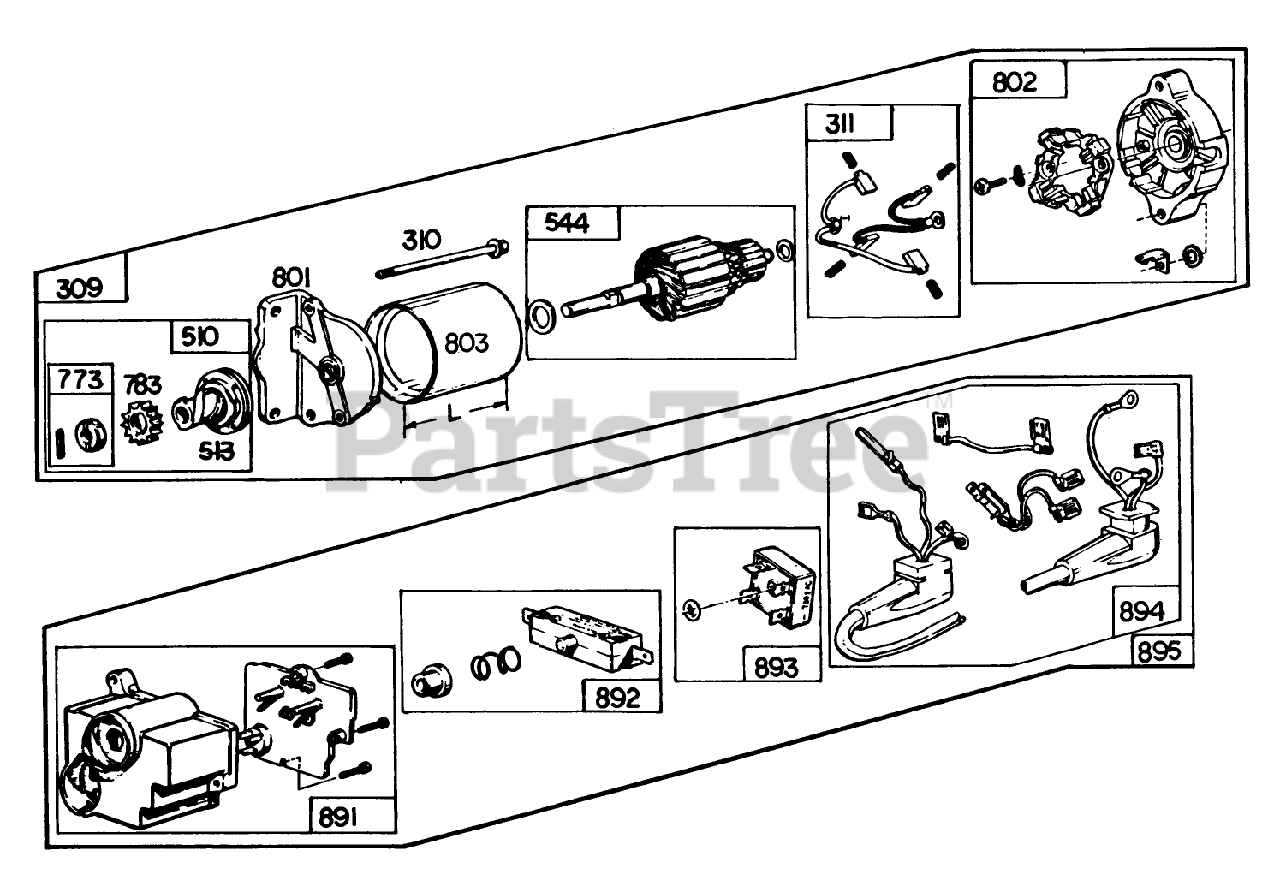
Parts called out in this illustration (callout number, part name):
309	Motor Drive Assembly
310	Thru Bolt Assembly
311	Brush Assembly
510	Drive Assembly
513	Clutch Assembly
544	Armature Assembly
773	Gear-Starter
801	Drive End Cap Assembly
802	Comm. End Cap Assembly
803	Housing Assembly
891	Housing Group
892	Switch Group
893	Rectifier
894	Lead Group
895	Control Group
